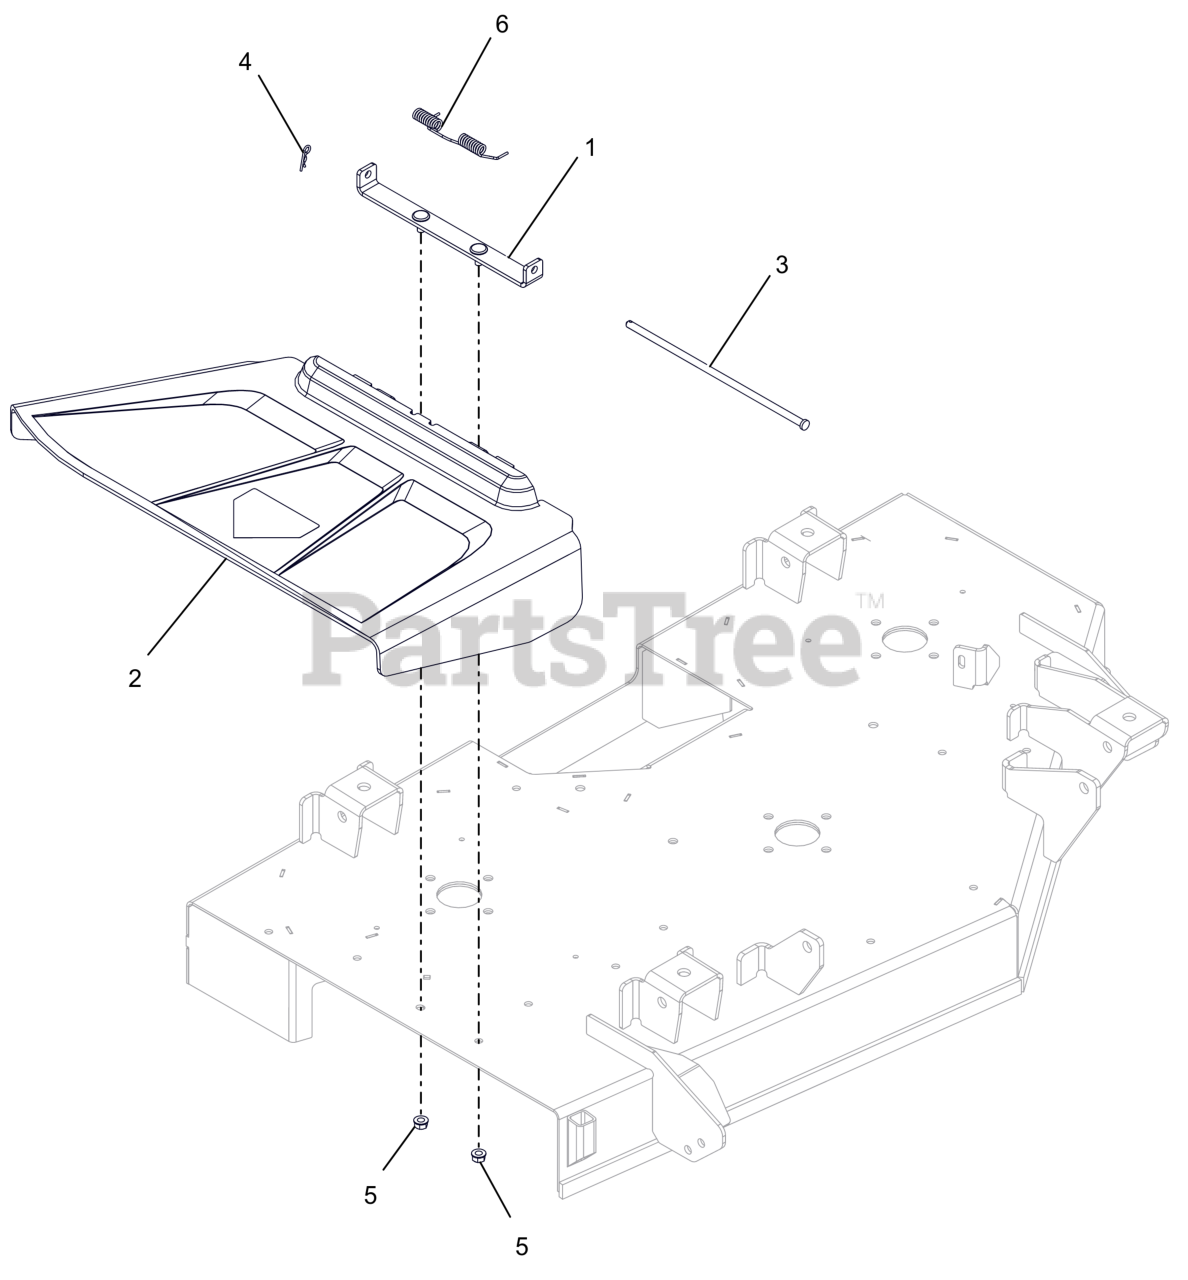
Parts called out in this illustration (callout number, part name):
2	CHUTE, SIDE DISCHARGE
3	PIN, 5/16 X 10.5
4	PIN, HAIR #213 .08X1.19 ZCC
5	NUT-LK-TOP-FLG .312-18 GF ZCC
6	SPRING-TORSION
